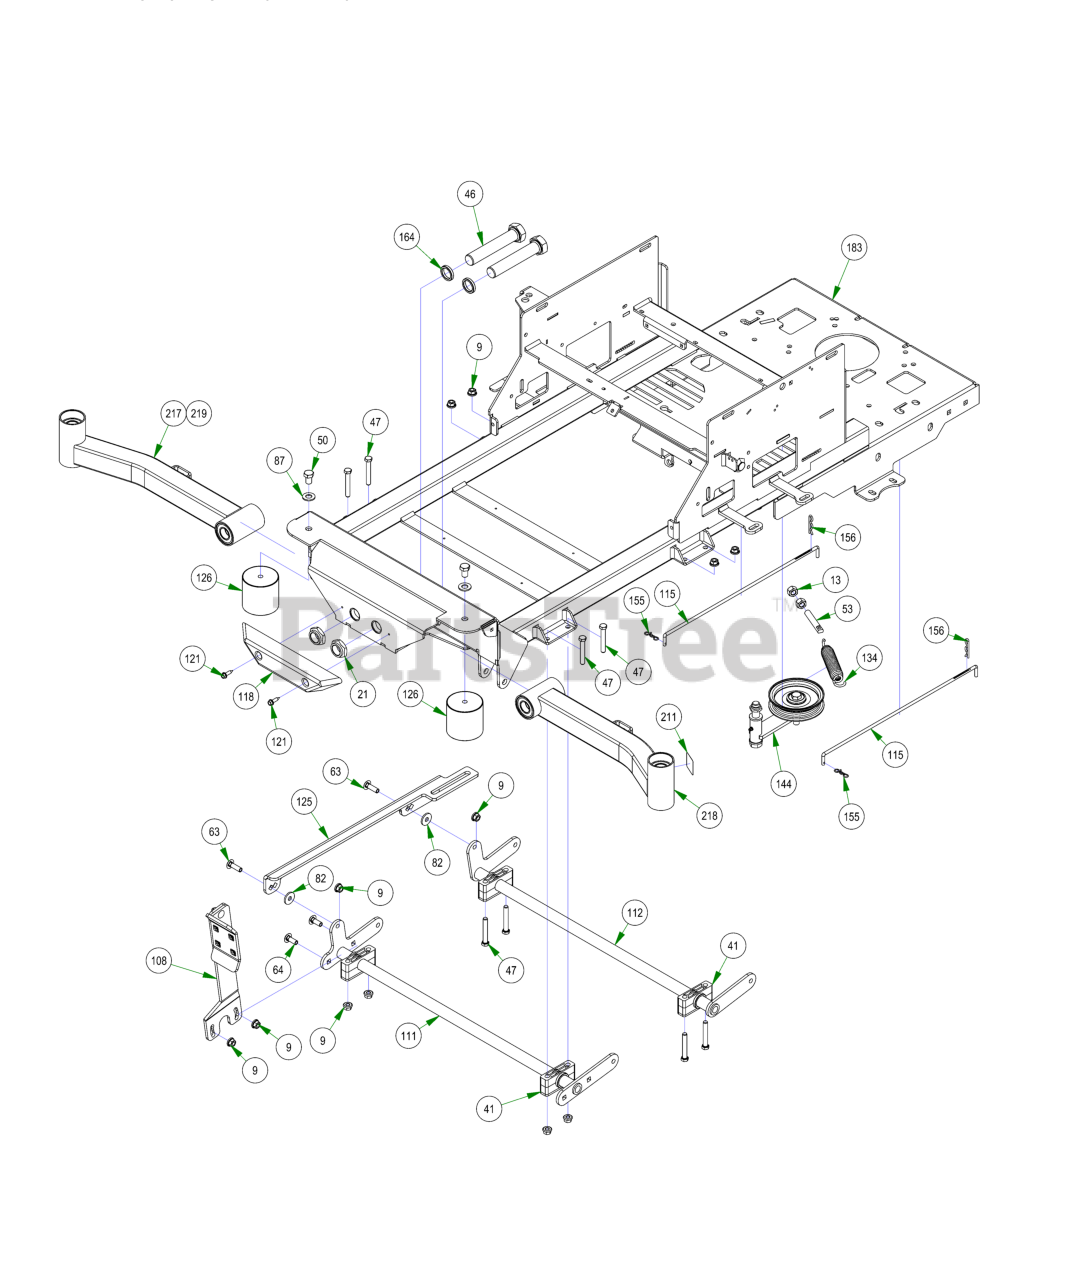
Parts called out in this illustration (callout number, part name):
9	3/8-16 NYLON INSERT FLANGE LOCKNUT (GR.F) ZINC
13	1/2-13 HEX NUT ZINC
21	1"-14 NYLON INSERT JAM LOCKNUT ZINC
41	Pillow Block Kit
46	1"-14 X 5-1/2 HEX CAP SCREW (GR.8) ZINC YELLOW
47	3/8-16 X 2-1/2 HEX CAP SCREW (GR.5) ZINC
50	1/2-13 X 3/4 HEX CAP SCREW (GR.5) ZINC
53	All Thread
63	3/8-16 X 1-1/4 CARRIAGE BOLT ZINC
64	3/8-16 X 1 CARRIAGE BOLT (GR.5) ZINC
82	.390 ID X 1.12 OD X .125 THK FLAT WASHER NYLON
87	1/2 SAE FLAT WASHER (1-1/16" OD) GR.8 ZINC YELLOW
108	Foot Pedal Assembly
111	Actuator Bar Front- 2017 MZ/ZT
112	Actuator Bar Rear- 2017 MZ/ZT
115	Neutral Rod
118	Bumper EZT
121	1/4 x 1 Hex Head Tek Screw
122	5/16-18 X 3/4 HEX WASHER SLOT (F) TCS ZINC
125	2017 MZ/ZT Actuator Linkage
126	Vibration Mount- Red Dot
134	Deck Idler Spring
144	ZT Pump Idler
156	Neutral Rod Clip
164	Spacer, 1x1.375x.25
183	2022 Suspension ZT Frame - Painted
211	Independetly Articulating Front Suspension Arms Patent Decal
217	2021 ZT Suspension Arm Assembly Short Right (48")
218	2021 ZT Suspension Arm Assembly Left (48", 54", & 60")
219	2021 ZT Suspension Arm Assembly Long Right (54" & 60")
